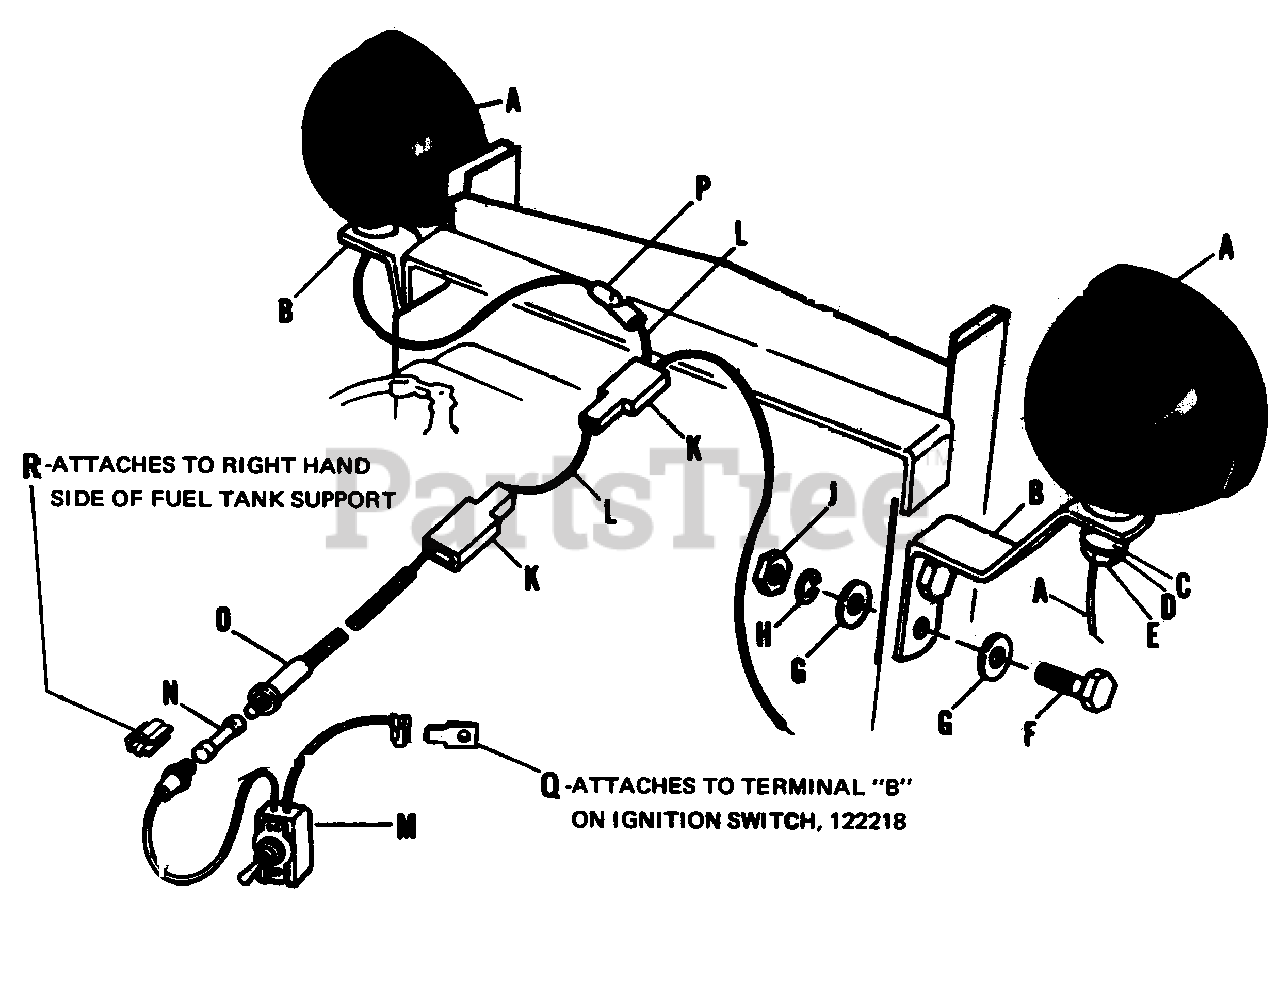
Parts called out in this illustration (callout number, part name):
A	Lamp Assembly
D	Lock Washer, l/2"
E	Full Hex, Nut, l/2"-13
F	Hex. Capscrew, 5/16" 18 x 1-1/2"
G	Plain Washer, 5/16"
H	Lock Washer, 5/16"
J	Full Hex, Nut, 5/16"-18
K	Insulated Connector
L	Extension Wire
M	Toggle Switch (with hardware)
N	Fuse 20 Amp.
O	Wire Connector
P	Connector
R	Fuse Clip
